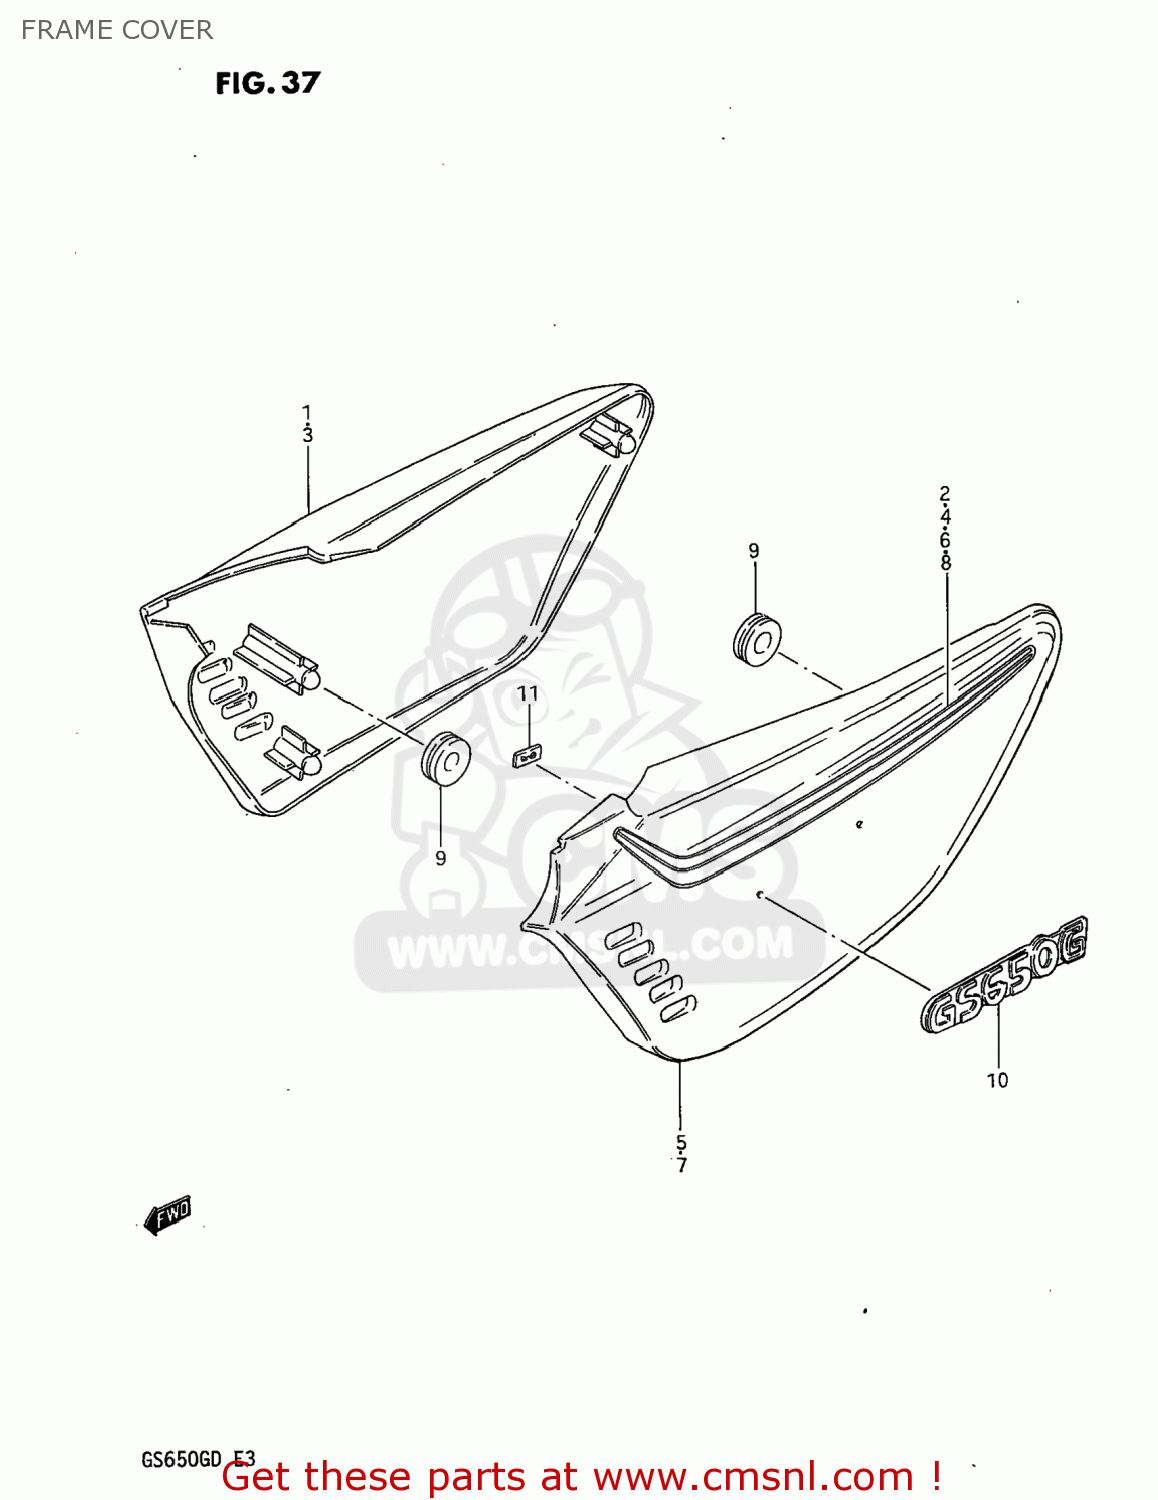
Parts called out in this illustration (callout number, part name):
1	COVER,FRAME,RIGHT
2	TAPE SET,FRAME COVER
3	COVER,FRAME,RIGHT
4	TAPE SET,FRAME COVER
5	COVER,FRAME,LEFT
6	TAPE SET,FRAME COVER,LEFT
7	COVER,FRAME,LEFT
8	TAPE SET,FRAME COVER
9	CUSHION
10	EMBLEM,FRAME COVER
11	NUT
